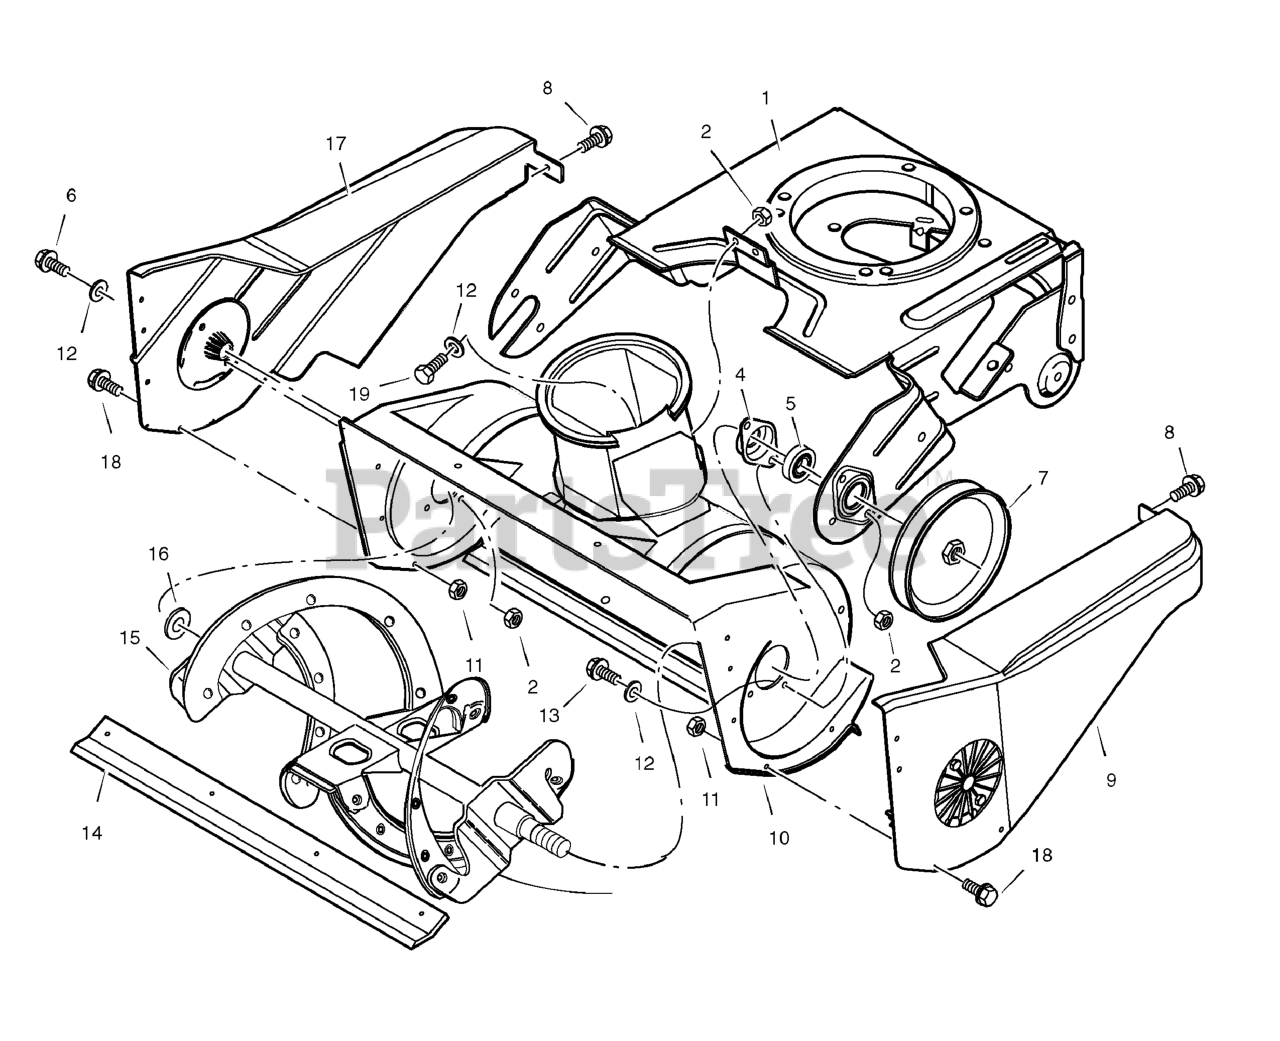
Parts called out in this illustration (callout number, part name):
1	Frame, Motor Box
4	Retainer, Bearing
5	Bearing
7	Pulley, Auger
9	Cover, Left Belt
10	Assembly, Auger Housing
11	Nut
12	Washer
14	Blade, Scraper
15	Auger Assembly
17	Cover, Right
